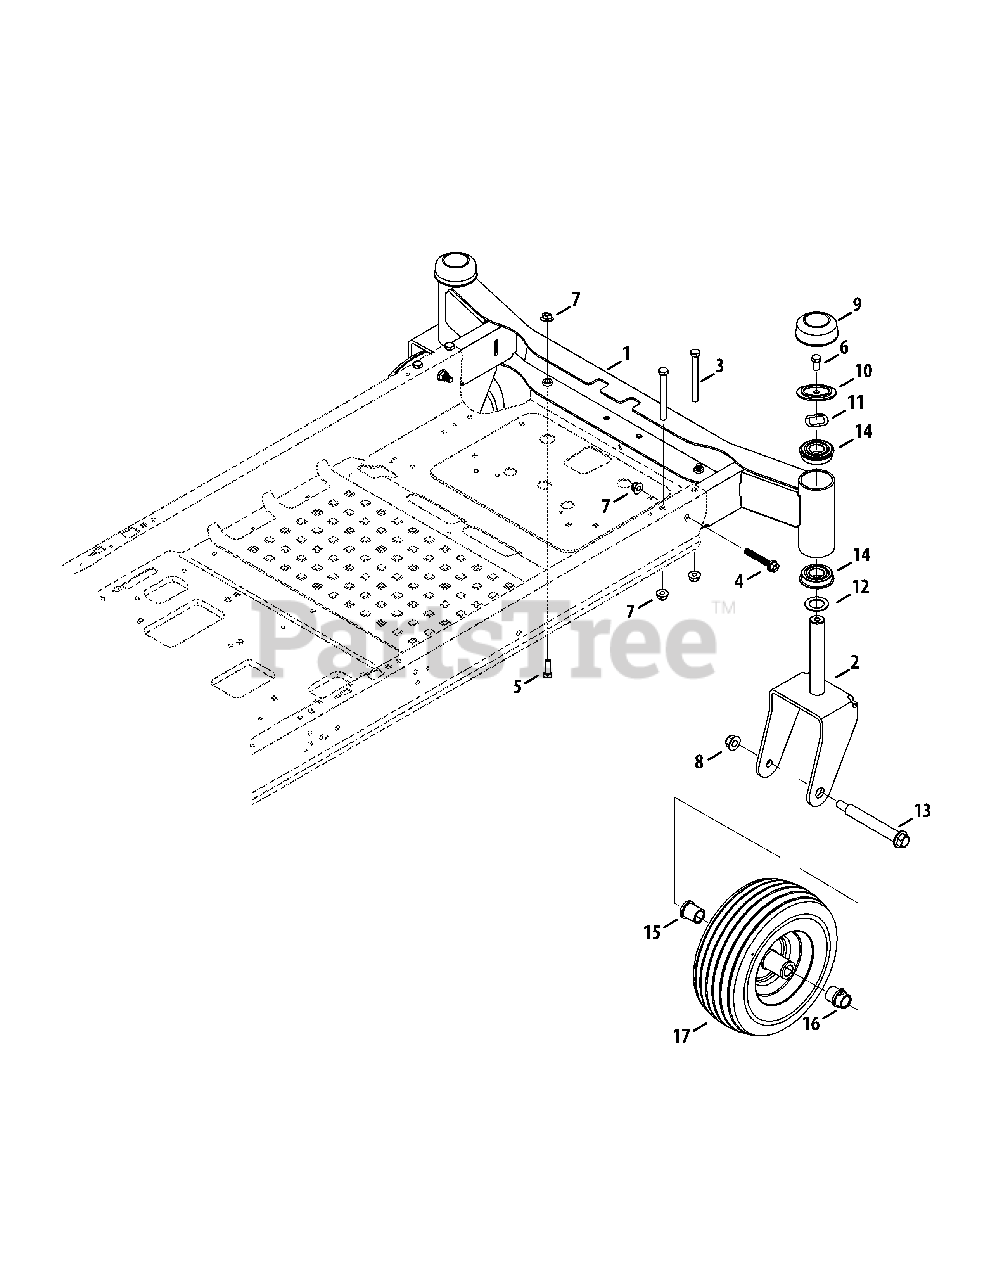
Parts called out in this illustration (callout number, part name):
2	Caster Wheel Bracket
3	Hex Cap Screw, 3/8-16 x 3.75
4	Hex Flange Screw, 3/8-16 x 2.00
5	Hex Cap Screw, 3/8-16 x 1.00
6	Hex Cap Screw, 3/8-16 x .750
7	Flange Lock Nut, 3/8-16
8	Flange Lock Nut, 1/2-13
10	Shoulder Spacer, 2.50 x .200
11	Wave Washer, 1.25 x 1.00 x .300
12	Flat Washer, 1.010 x 1.56 x .060
13	Shoulder Screw, 1/2-13
14	Ball Bearing
15	Flange Bearing, .76 x 1.0 x 1.2
16	Flange Bearing, .76 ID w/Lube Fitting
17	Wheel Assembly, 11.0 x 4.0 x 5.0
